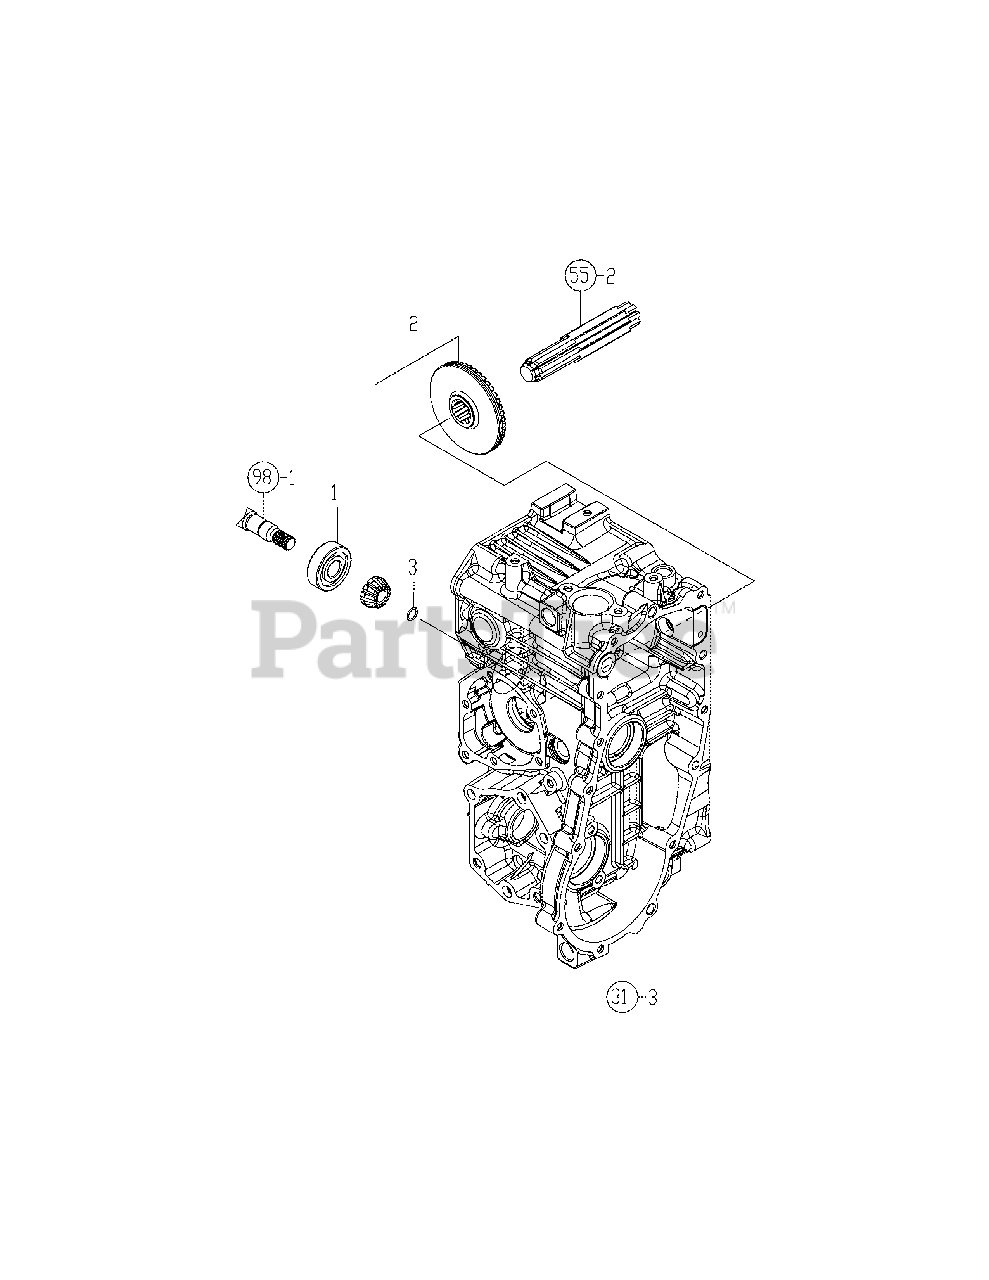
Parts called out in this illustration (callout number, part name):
1	Bearing, 6303Rsh2
2	Gear Kit, Input
3	Ring, 12 X 1.6
